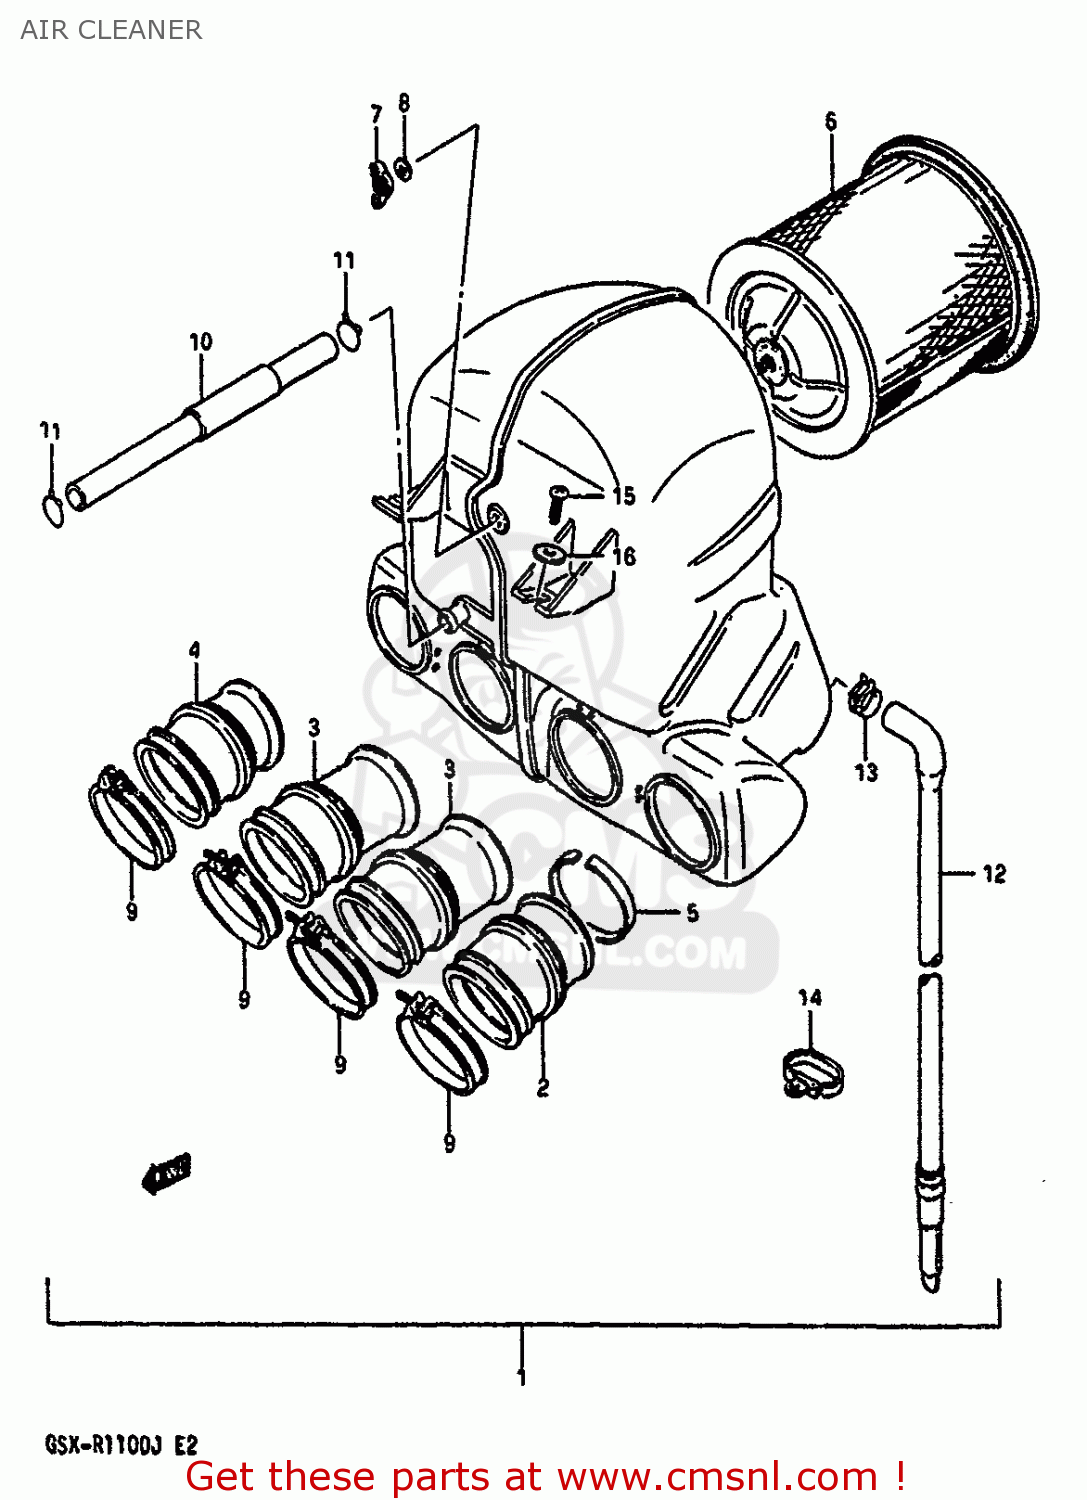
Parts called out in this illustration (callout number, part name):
1	CLEANER ASSEMBLY,AIR
2	TUBE,OUTLET,L
3	TUBE,OUTLET MIDDLE,L/R
4	TUBE,OUTLET,R
5	RING
6	FILTER
7	NUT, WING
8	WASHER 5MM
9	CLAMP
10	TUBE,BREATHER
11	CLIP
12	DRAIN TUBE
13	CLIP
14	CLAMP,AIR CLEANER DRAIN TUBE
15	SCREW
16	WASHER
